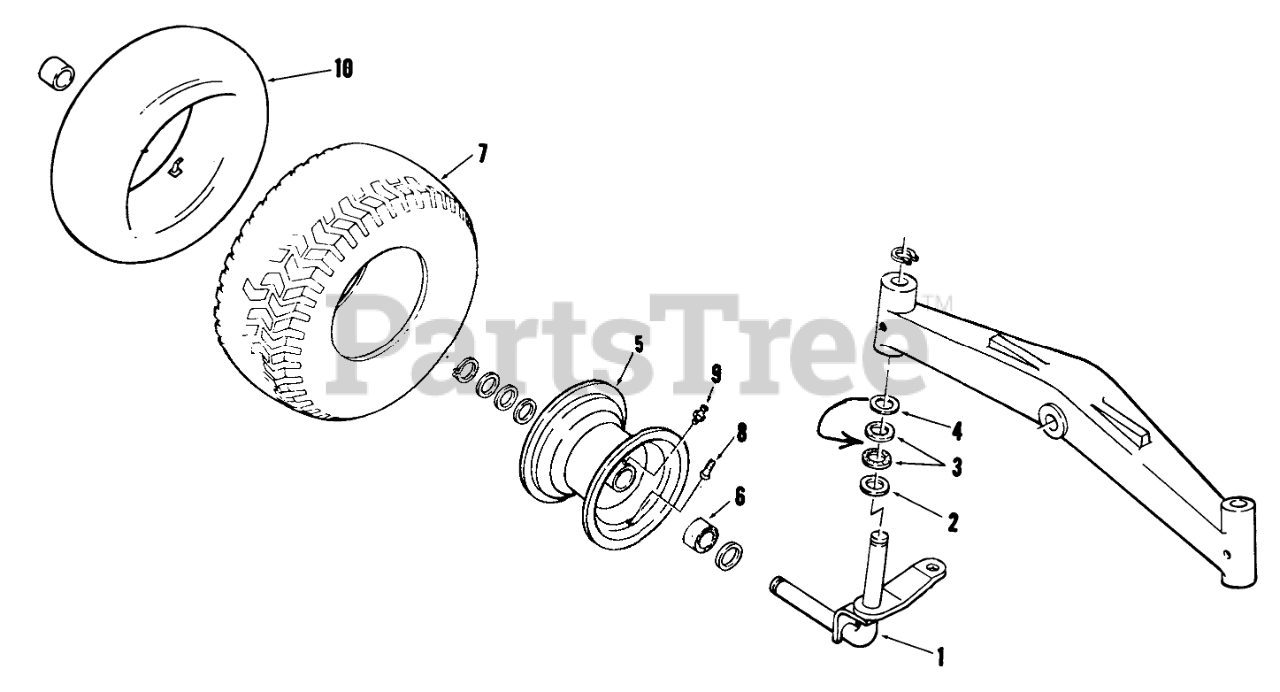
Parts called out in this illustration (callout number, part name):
1	Spindle, R.H.
1	Spindle, L.H.
2	Race Thrust
3	WASHER-SLIP
4	WASHER
5	Wheel
6	BEARING-RADIAL FLNGE
7	TIRE TURF SAVER 16X6.50-8
8	VALVE
9	Zerk
10	Tube
